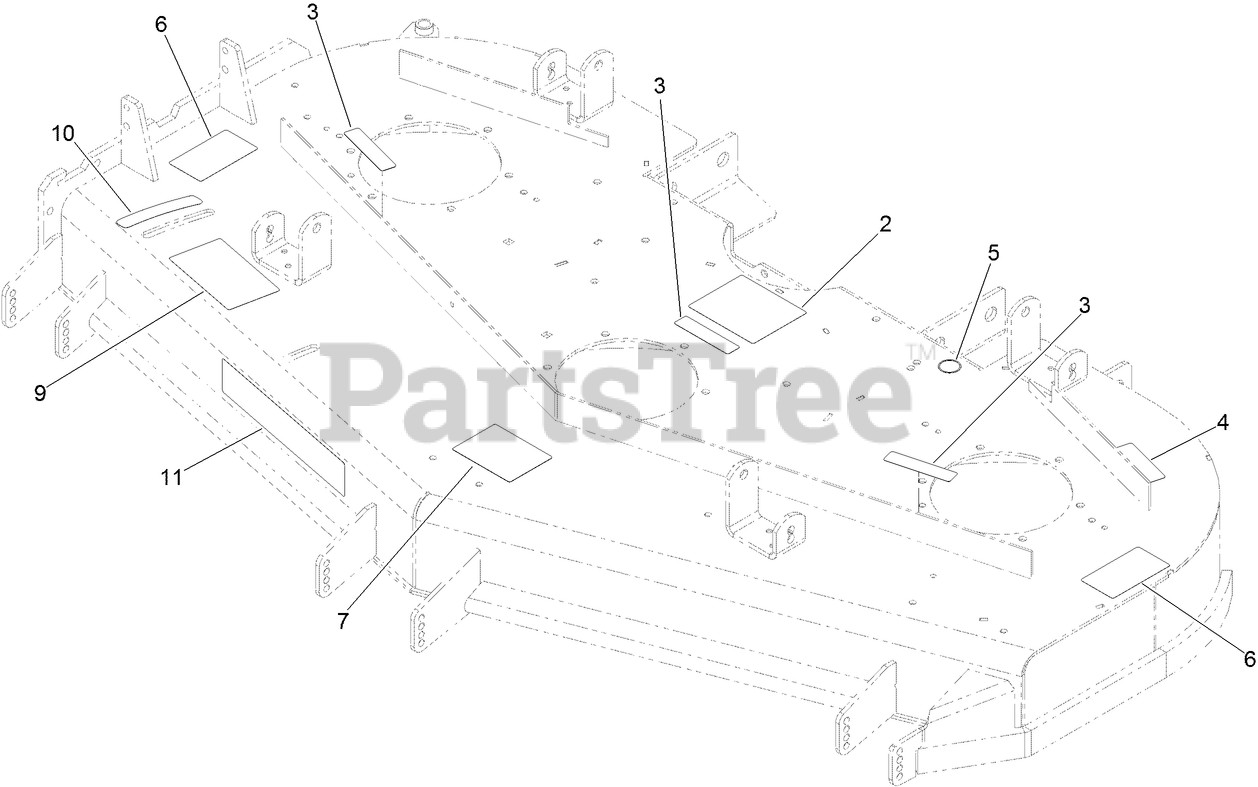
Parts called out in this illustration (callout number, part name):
2	DECAL-ROUTING, BELT
3	DECAL-WARNING
4	DECAL-BOLT TORQUE
5	DECAL-GREASE
6	DECAL-DANGER
7	DECAL-SCALP, ANTI
9	DECAL-ADJUSTMENT, BAFFLE
10	DECAL-SETTING, BAFFLE
